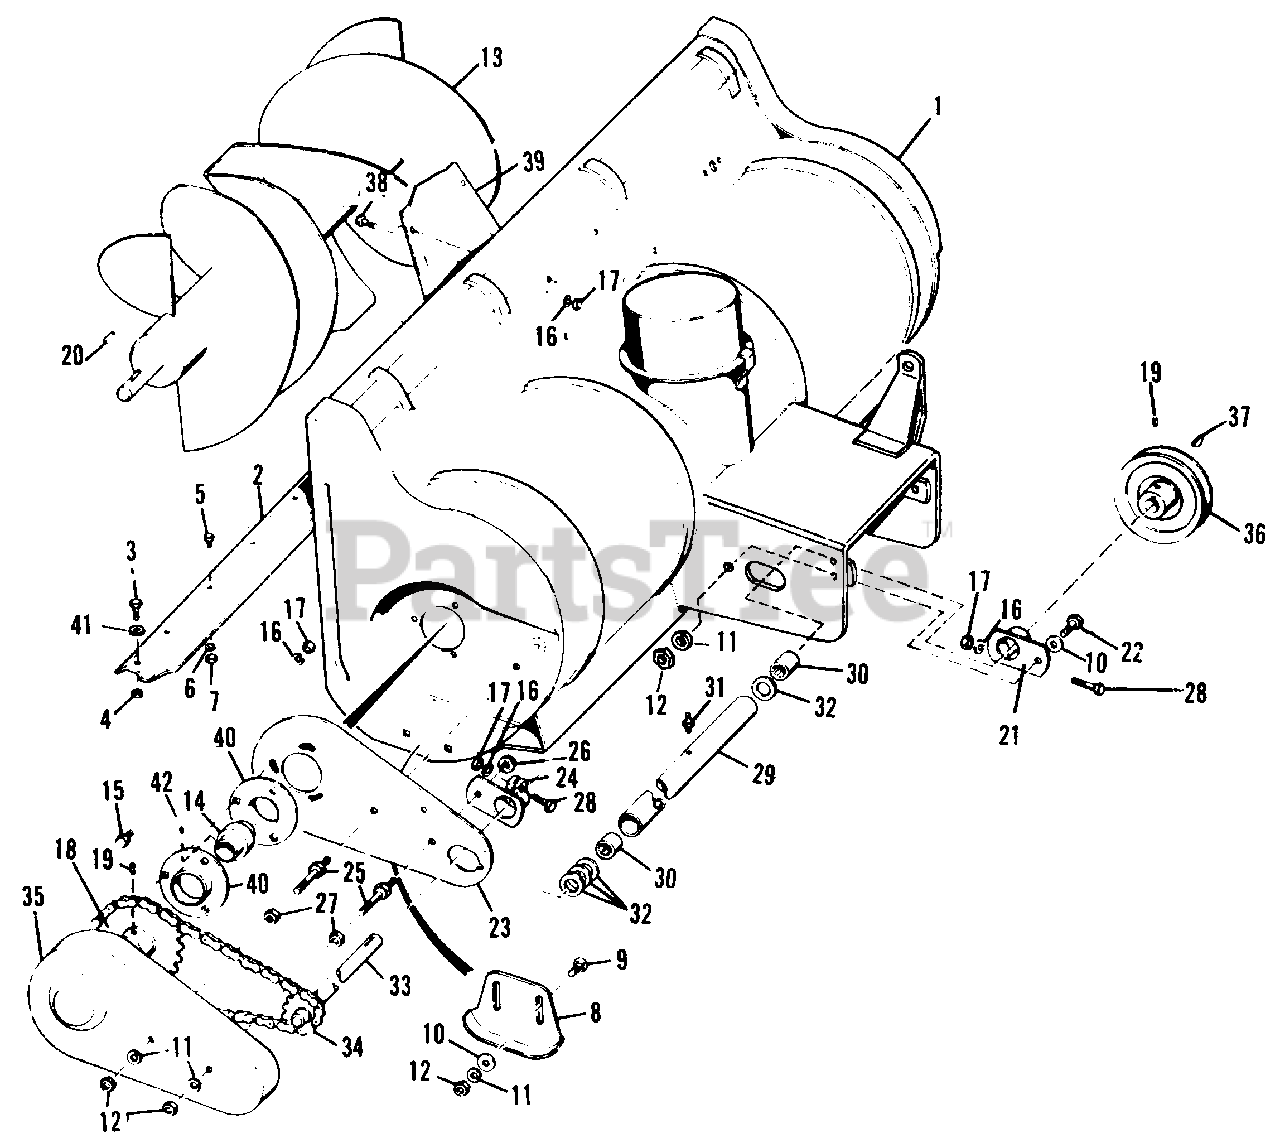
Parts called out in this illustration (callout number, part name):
1	Body Assembly
2	Body Scraper
3	Hex Capscrew, 5/16"-18 x 5/8"
4	Full Lock Hex Nut 5/16"-18
5	Hex Capscrew, 1/4"-20 x 5/8"
6	Lock Washer 1/4"
7	Full Hex Nut 1/4"-20
9	Carriage Bolt, 3/8"-16 x 3/4"
10	Plain Washer, 3/8"
11	Lock Washer, 3/8"
12	Full Hex Nut, 3/8"-16
13	Rotor Assembly
14	Bearing Cartridge w/713509 Set Screw
15	Hex Capscrew, 5/16"-18 x 3/4"
16	Lock Washer 5/16"
17	Full Hex Nut, 5/16"-18
18	Rotor Sprocket
19	Set Screw, 5/16"-18 x 5/16"
21	Support Assembly Clamp
22	Hex Capscrew, 3/8"-16 x 1
23	Side Plate
24	Support Assy. Clamp
26	Nut, Flange, 3/8"-16
27	Full Lock Hex Nut 3/8"-16
28	Hex Capscrew 5/16"-18 x 1-1/2"
29	Bearing Housing
30	Needle Bearing
31	Grease Fitting
33	Shaft Assembly
35	Chain Guard
37	Key 3/16" dia. x 3/4"
38	Hex Capscrew, 5/16"-18 x 5/8"
40	Bearing Flange
42	Set Screw 5/16"-18 x 5/16"
